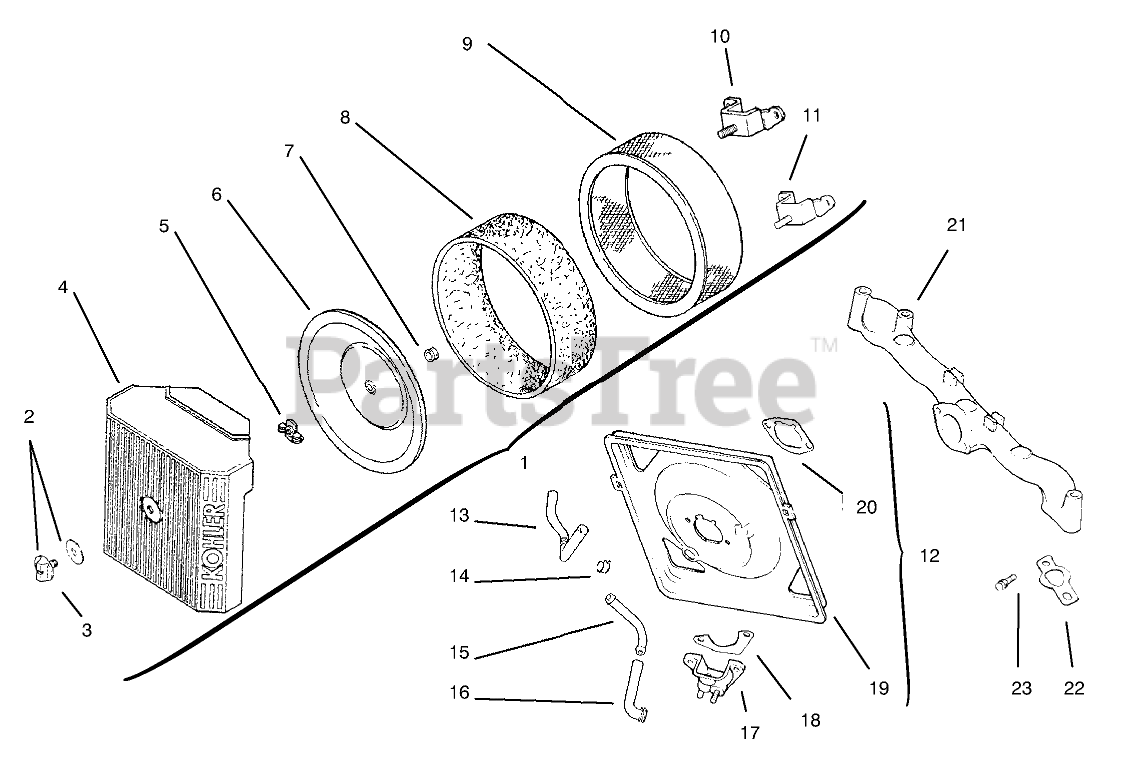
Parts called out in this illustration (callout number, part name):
1	Kit-Air Cleaner Cover
2	Kit-Knob w/Gasket
3	Knob-Cover
4	Cover-Air Cleaner
5	Wingnut
6	Cover-Inner AirCleaner
7	Seal, insert
8	Bement-Precleaner
9	Bement-Air Cleaner
10	Bracket-Air Cleaner
11	Bracket-Air Cleaner
12	Kit-Air Cleaner Base
13	Hose-Breather
14	Clamp
15	Fitting
16	Hose-Breather
17	Cup-Fuel Spitback
18	Gasket-Fuel Spitback
19	Base-Air Cleaner
20	Gasket-A/C Base
21	Manifold-Intake
22	Gasket-Intake, Manifold
23	Screw
